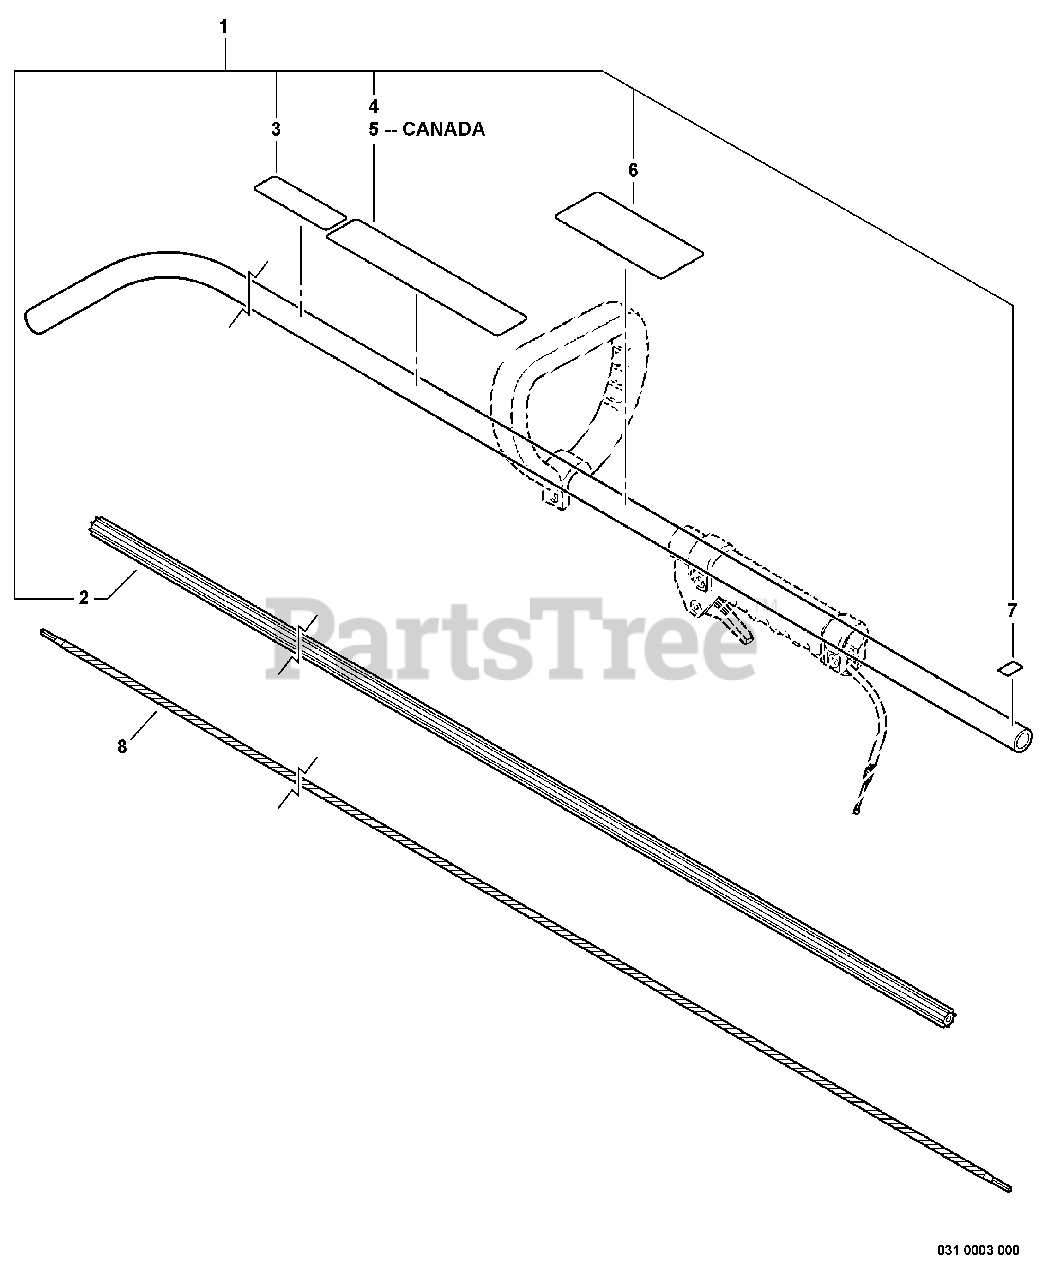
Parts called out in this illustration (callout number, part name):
1	MAIN PIPE ASSY
2	LINER - FLEXIBLE
3	LABEL - CAUTION -- SPANISH
4	LABEL - CAUTION
5	LABEL - CAUTION
6	LABEL - HANDLE LOCATION
7	LABEL - ALIGNMENT
8	DRIVESHAFT - FLEXIBLE
